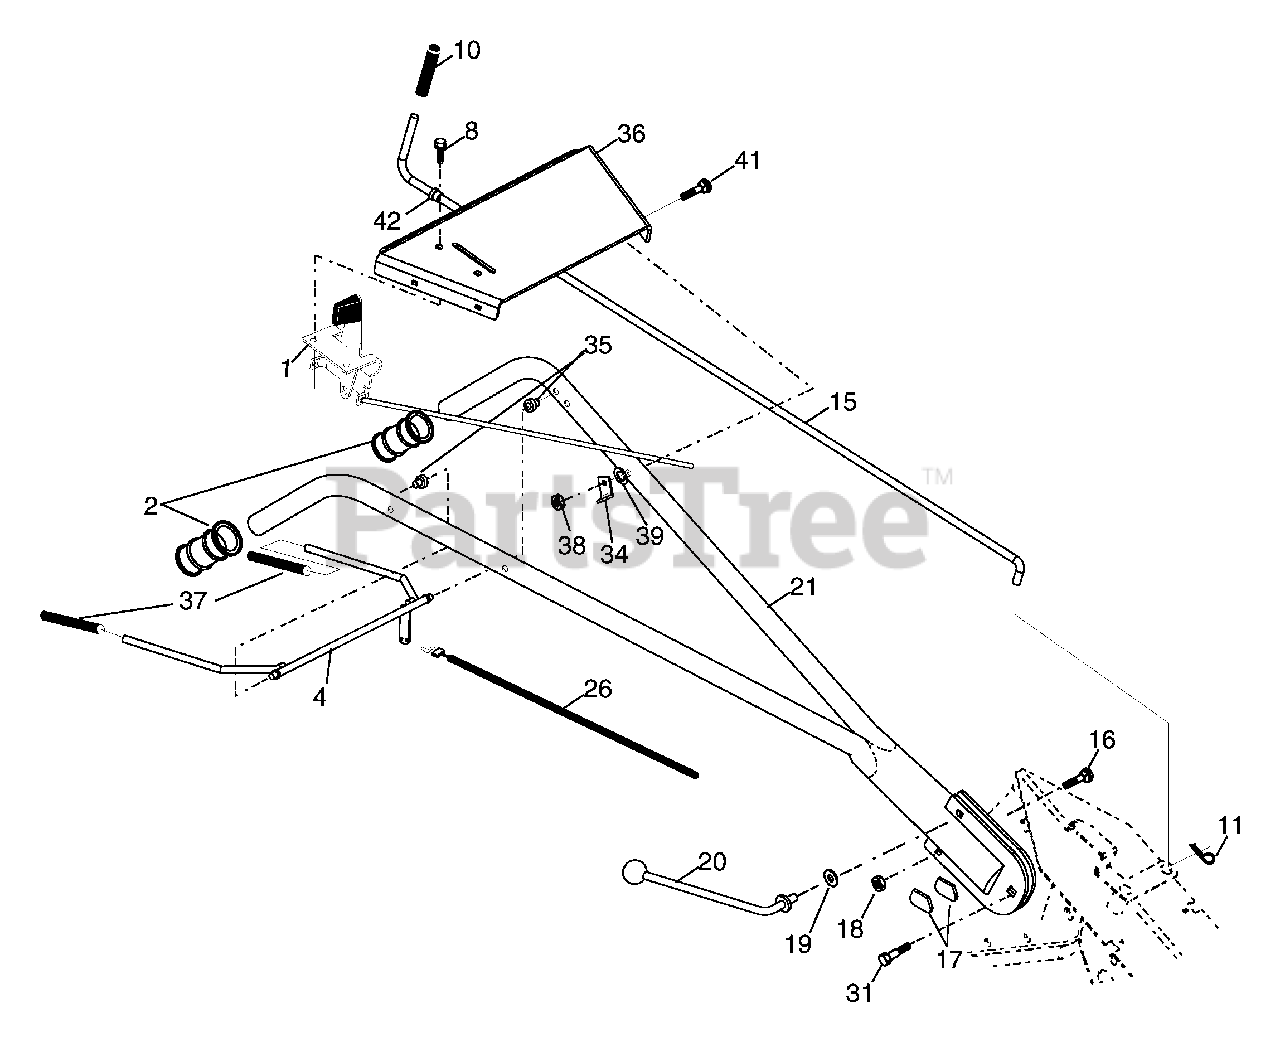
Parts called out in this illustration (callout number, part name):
1	Control, Throttle
2	Grip, Handle
4	Bar, Control
8	Screw
10	Grip, Handle
11	Clip, Hairpin
15	Rod, Shift
16	Bolt, Carriage 3/8-16 x 1 Gr. 5
17	Lock, Handle
18	Nut Crownlock 3/8-16 UNC
19	Washer 13/32 x 1 x 11 Ga.
20	Lever, Lock, Handle
26	Cable, Clutch
31	Bolt, Pivot
34	Bracket, Clutch Cable
35	Grommet, Handle
36	Bracket, Handle
37	Grip, Bar Control
38	Locknut 5/16-18
39	Washer, Lock 5/16
41	Bolt, Carriage 5/16-18 x 1-3/4
42	Bushing, Snap
